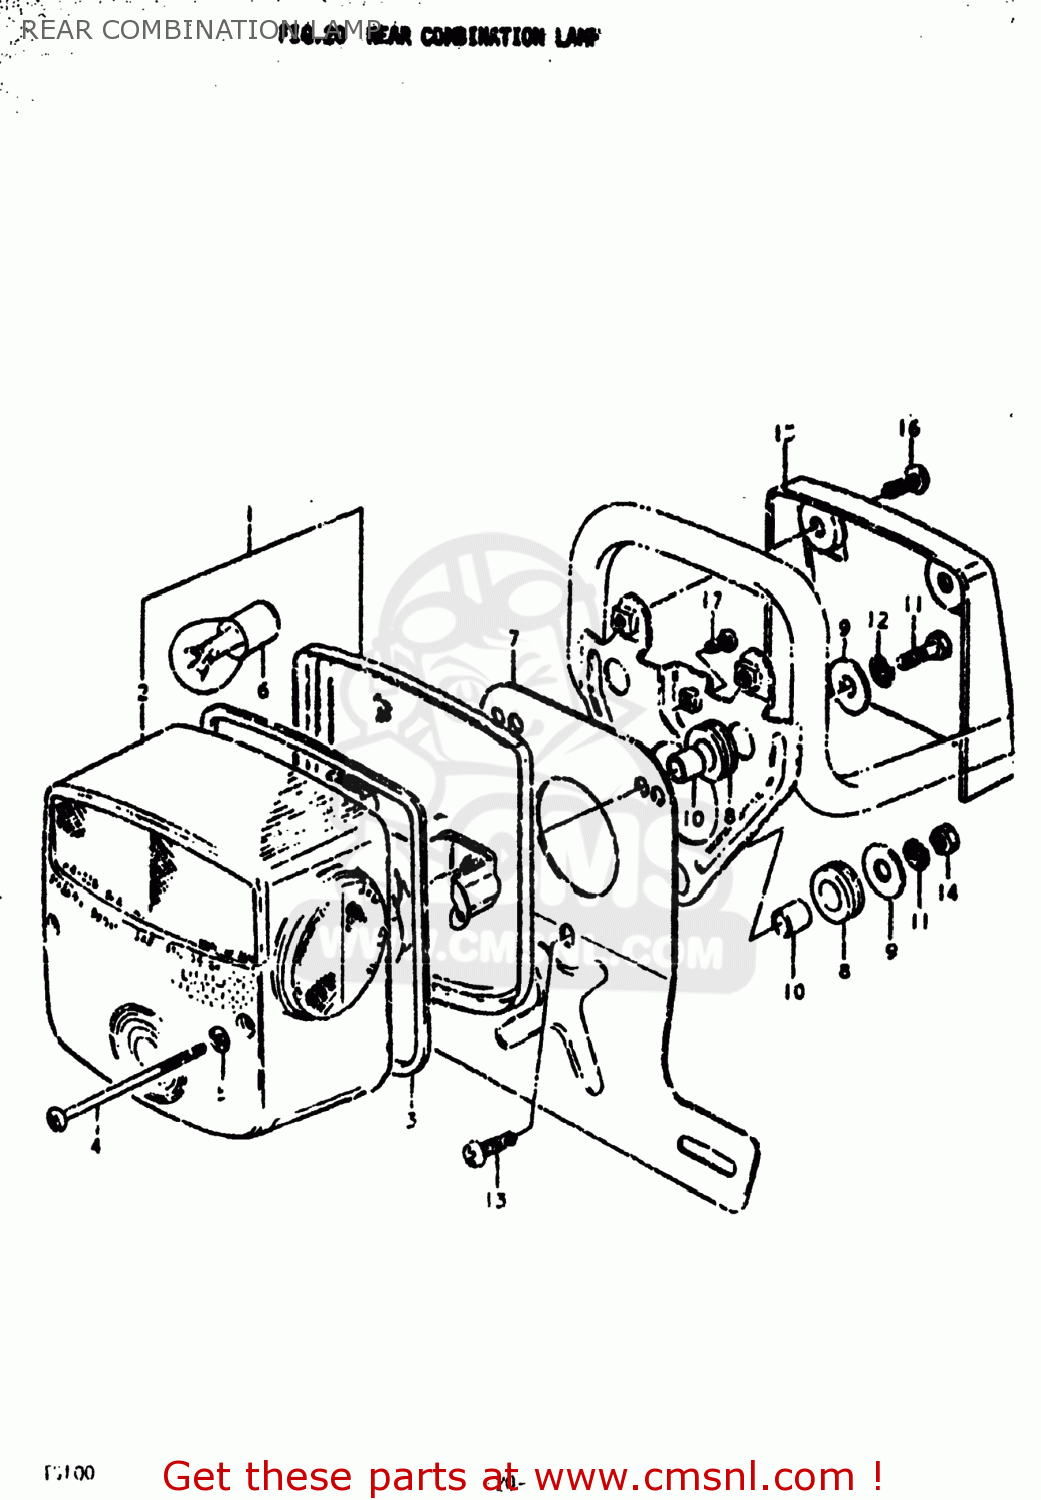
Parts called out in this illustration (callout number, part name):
1	LAMP ASSEMBLY,REAR COMBINATION
2	LENS,REAR COMBINATION LAMP
3	GASKET (NAS)
4	SCREW
5	GASKET (NAS)
6	BULB(6V32/3CP,STANLEY)
7	BRACKET,LICENSE PLATE
8	CUSHION
9	WASHER (6.5X24X1.6)
10	SPACER,REAR COMBINATION LAMP
11	BOLT
12	LOCK WASHER
13	SCREW
14	NUT
15	COVER
16	SCREW 6X12
